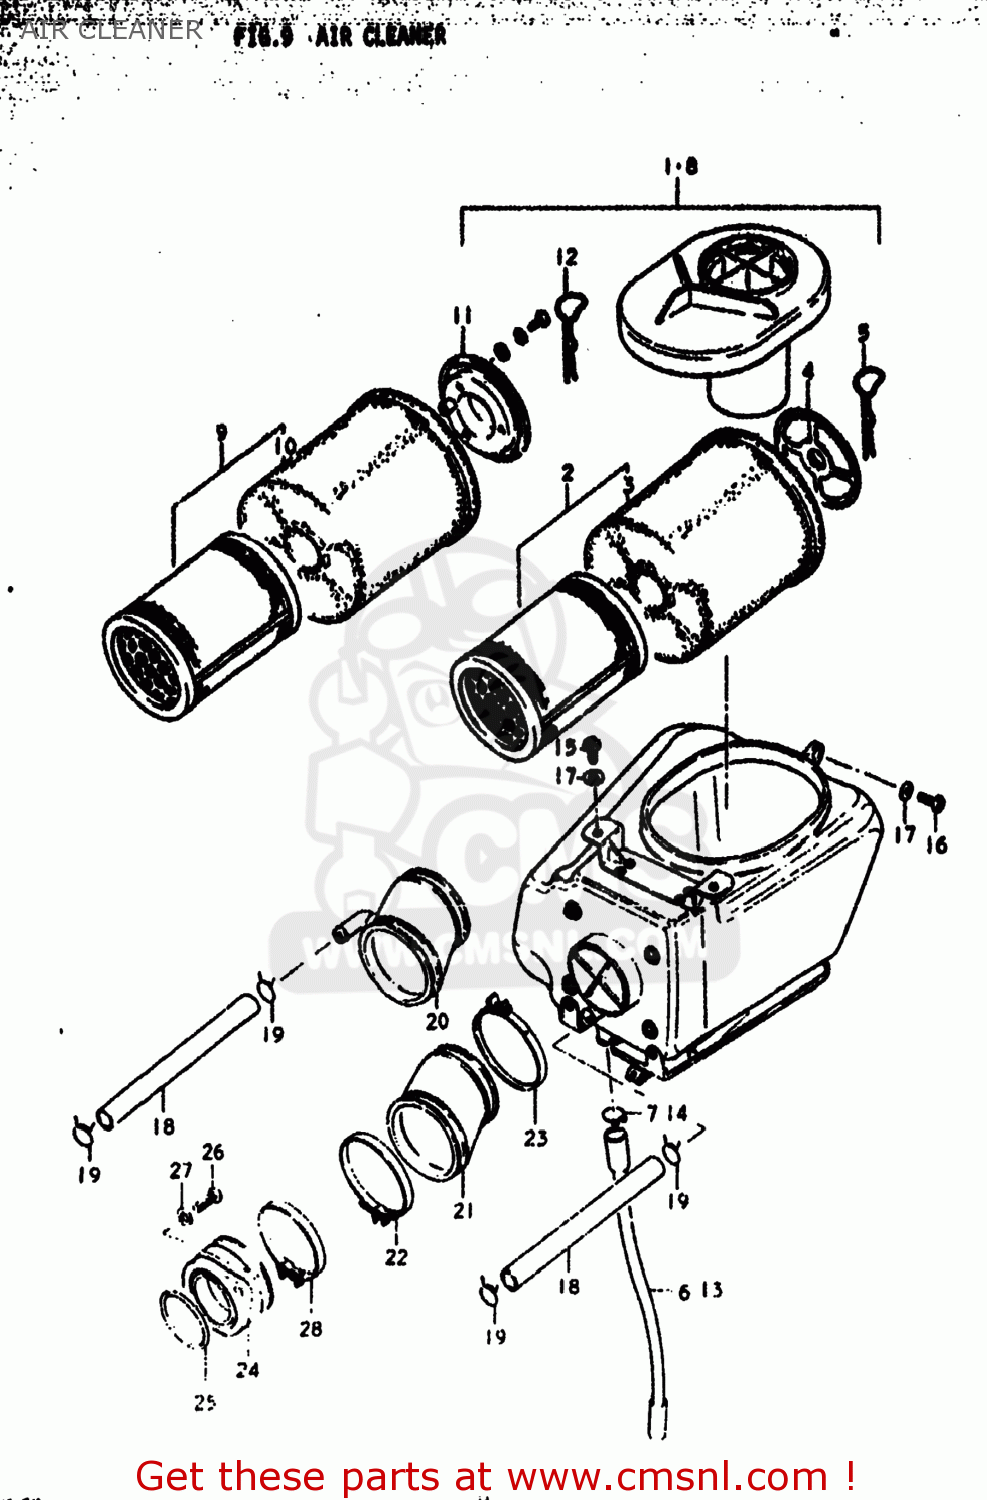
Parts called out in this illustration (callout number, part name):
1	CLEANER ASSEMBLY,AIR
2	FILTER,AIR CLEANER
3	ELEMENT,AIR CLEANER
4	HOLDER,FILTER
5	SPRING,AIR CLEANER
6	HOLDER,FILTER
7	HOSE,AIR CLEANER
8	CLEANER ASSEMBLY,AIR
9	FILTER,AIR CLEANER
10	ELEMENT,AIR CLEANER
11	HOLDER,FILTER
12	SPRING,AIR CLEANER
13	HOLDER,FILTER
14	HOSE,AIR CLEANER
15	SCREW
16	SCREW
17	WASHER 6MM
18	HOSE
19	CLIP
20	TUBE,AIR CLEANER OUTLET
21	TUBE,AIR CLEANER OUTLET
22	CLAMP
23	CLAMP
24	PIPE,INTAKE
25	O-RING (D:2.4 ID:39.7)
26	SCREW
27	LOCK WASHER
28	CLAMP
